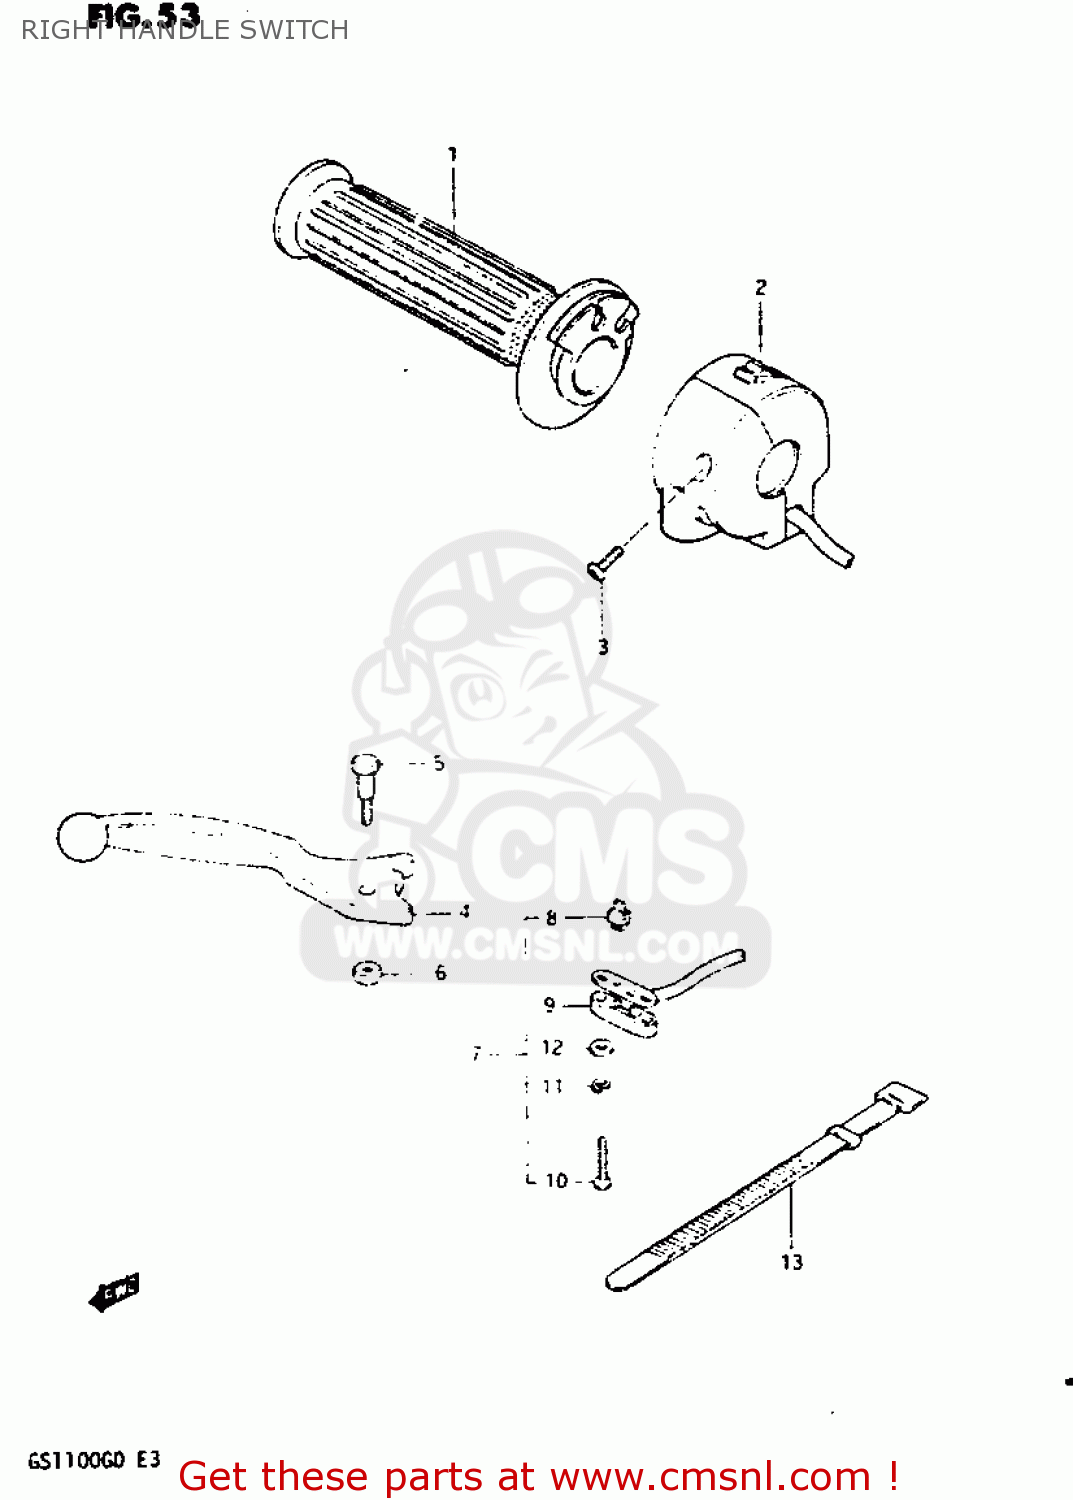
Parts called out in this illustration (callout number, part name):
1	GRIP,THROTTLE
2	SWITCH ASSY,HANDLE,R
3	SCREW
4	LEVER,BRAKE
5	BOLT
6	NUT 6MM
7	SWITCH ASSEMBLY
8	CONTACT,SWITCH
9	COVER,FR BK TERMINAL BASE
10	SCREW
11	WASHER,LOCK
12	WASHER
13	CLAMP(L:120)
